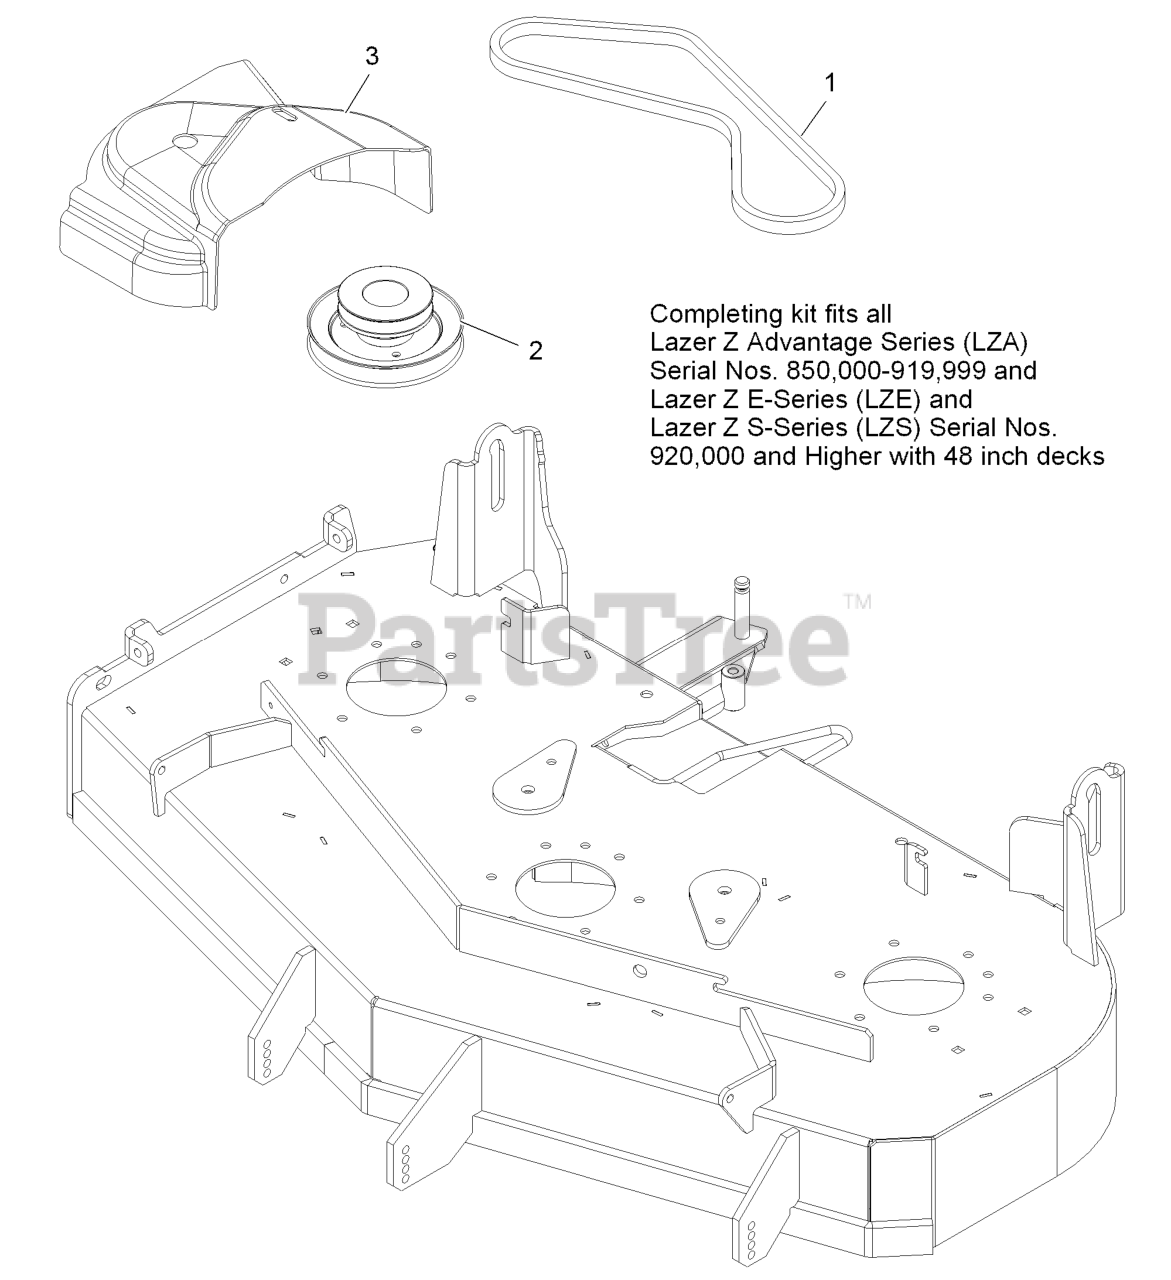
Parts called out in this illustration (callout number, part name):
1	BELT-BLOWER
2	JACKSHAFT-UV DRIVE, 484 S
3	COVER,BELT UV 48
